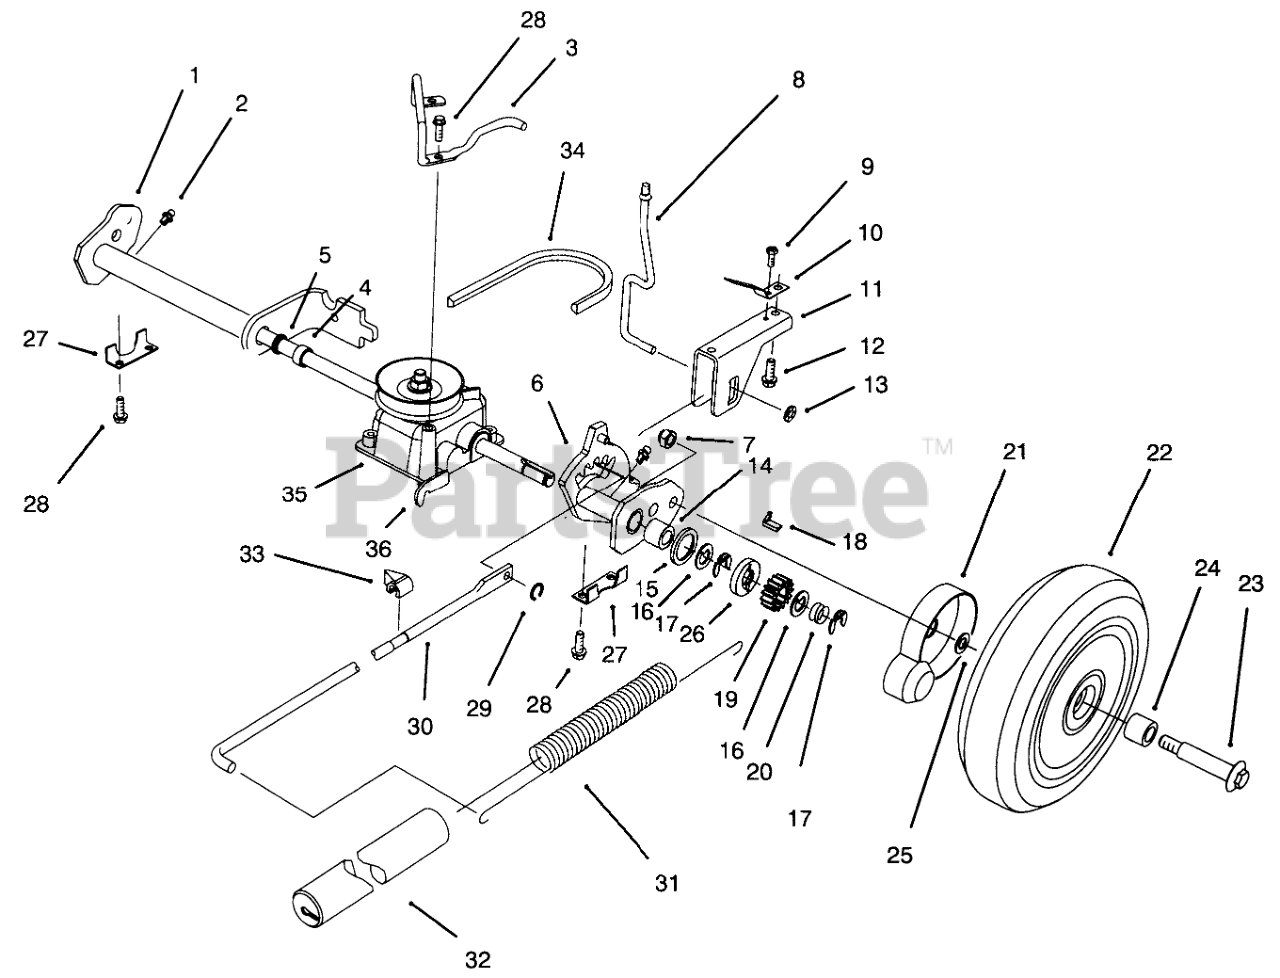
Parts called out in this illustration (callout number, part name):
1	Rear Pivot Assembly R.H. (Incl. Ref. #2, 4, 5 & 14)
2	FITTING-GREASE
3	Retainer Belt
4	BUSHING
5	SEAL-OIL
6	Rear Pivot Assembly L.H. (Incl. Ref. #2, 4, 5 & 14)
7	NUT-HEX
8	TRIGGER ROD
9	SCREW 8 - 32 X 250
10	SPRING - TRIGGER RET
11	SADDLE - HOC
12	SCREW
13	PUSHNUT
14	BEARING-ROLLER
15	RING-FRICTION
16	WASHER-THRUST, KEYED
17	RING-CLIP, LOCKING
18	KEY-ROCKING, LH
19	GEAR-PINION
20	SPRING-COMPRESSION
21	COVER-WHEEL
22	Wheel, Tire & Gear Assy. (Incl. Ref. #24)
23	BOLT-WHEEL
24	BUSHING
25	SPACER-COVER, WHEEL
26	WASHER-CLUTCH
27	REAR SECURING PLATE
28	SCREW-HWH
29	GRIP RING
30	LINK ROD
31	SPRING-COUNTERBALANCE
32	COVER-SPRING
33	INDICATOR-HEIGHT OF CUT
34	V-BELT
35	Gearcase Assembly (Incl. Ref. #36)
36	Frame
